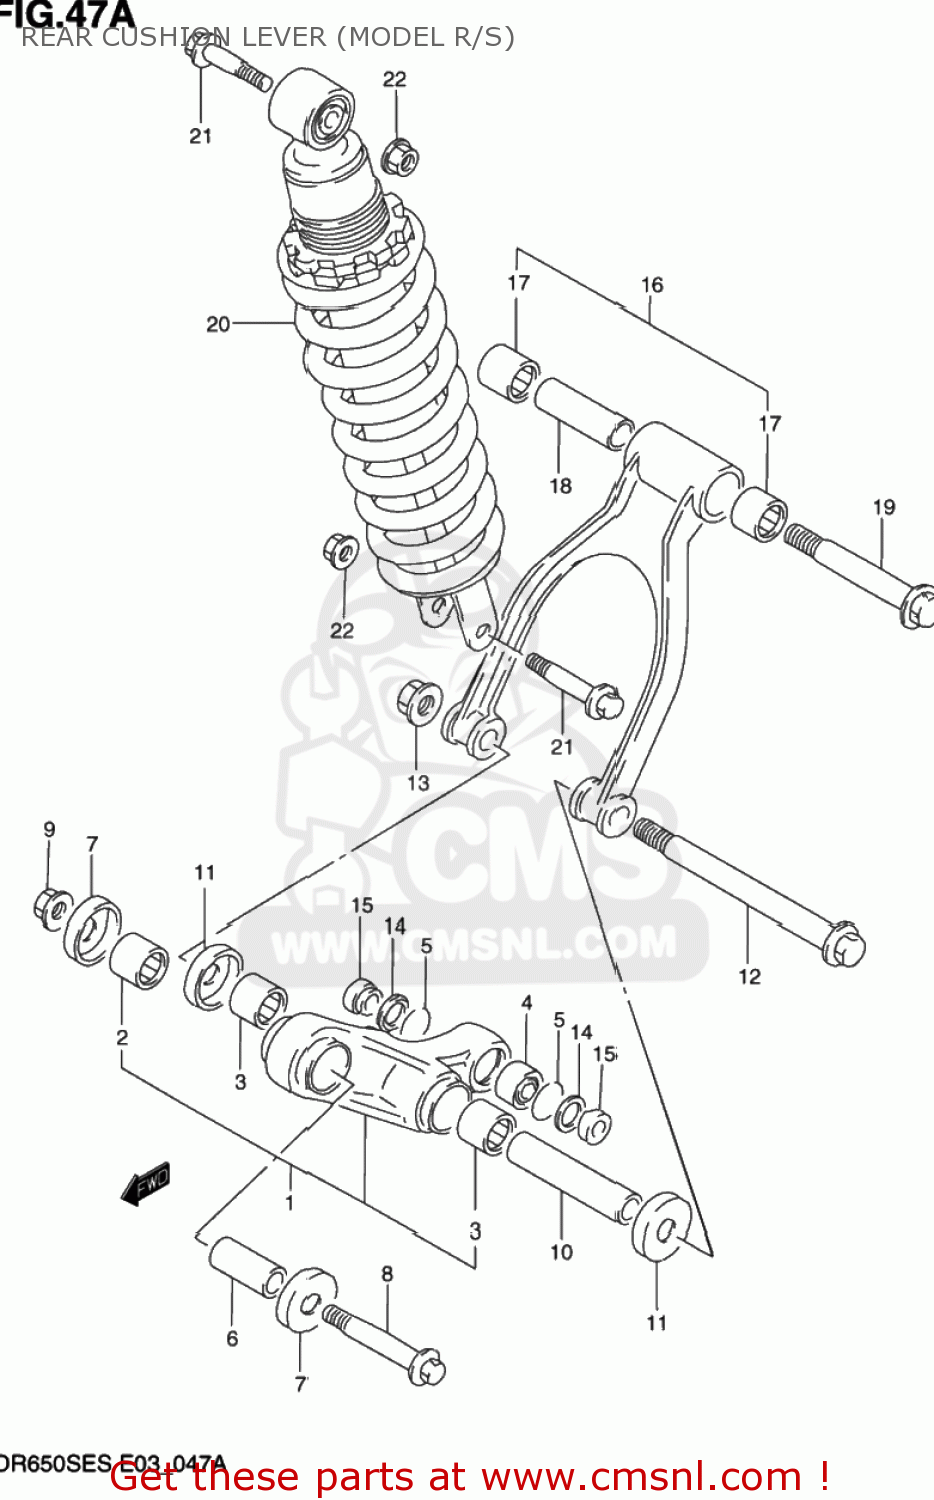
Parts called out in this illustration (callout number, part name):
1	LEVER SET,REAR CUSHION
2	BEARING(20X27X30)
3	BEARING(20X27X23.5)
4	BEARING,RR CUSHION LEVER
5	RING,STOPPER
6	SPACER,RR CUSHION LEVER FR
7	SEAL,RR CUSHION LEVER FR DUST
8	BOLT,RR CUSHION LEVER FR
9	NUT 12MM
10	SPACER (14X20X78)
11	SEAL,RR CUSHION LEVER CTR DUST
12	BOLT,RR CUSHION ROD LWR
13	NUT
14	SEAL,DUST RR SHOCK ABSORBER
15	COLLAR
16	ROD SET,REAR CUSHION,LEFT
17	BEARING(20X27X23.5)
18	SPACER (14X20X63)
19	BOLT,RR CUSHION ROD UPR
20	ABSORBER ASSY,RR SHOCK
21	BOLT(10X52)
22	NUT
